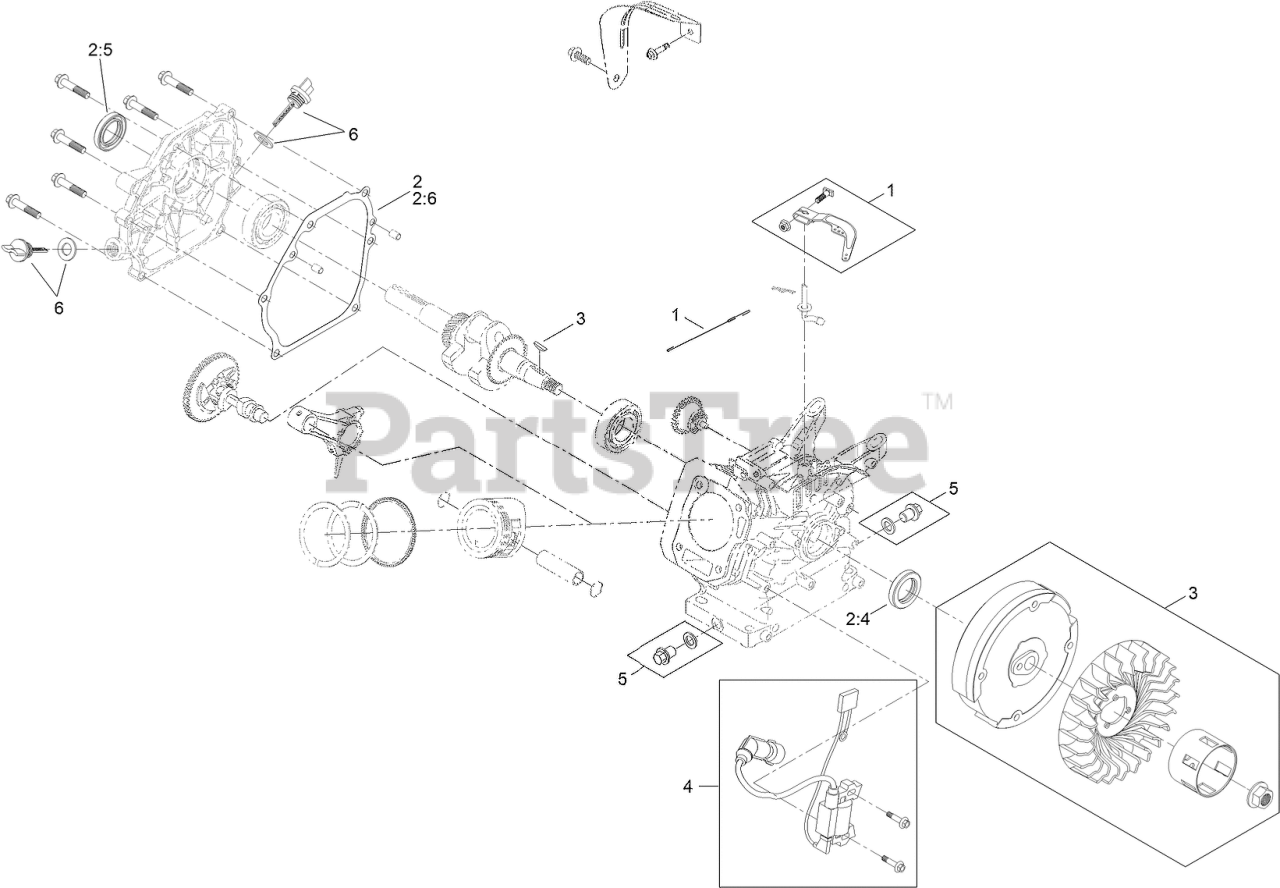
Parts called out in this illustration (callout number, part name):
1	GOVERNOR KIT
2	GASKET AND SEAL KIT
2:1	GASKET-COVER, VALVE
2:2	Gasket-Exhaust
2:3	GASKET-HEAD, CYLINDER
2:4	Seal-Oil
2:5	Seal-Oil
2:6	GASKET-COVER, CRANKCASE
2:7	GASKET-CARBURETOR
2:8	GASKET-CARBURETOR
2:9	GASKET-CARBURETOR
3	RECOIL FLYWHEEL KIT
4	IGNITION KIT
5	DRAIN PLUG KIT
6	OBS DIPSTICK AND O-RING KIT
